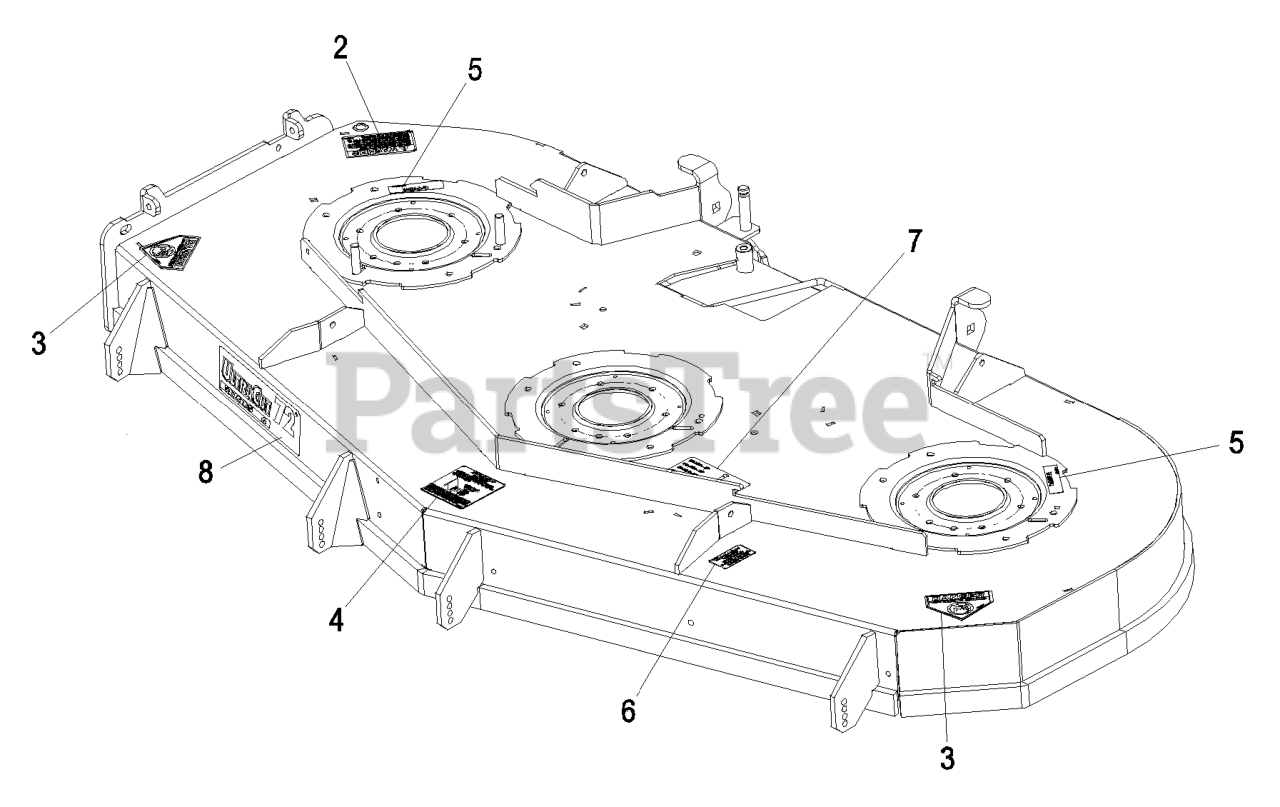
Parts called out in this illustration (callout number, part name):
2	DECAL-WARNING, DISCHARGE
3	DECAL-DANGER
4	DECAL,ANTISCALP
5	DECAL-COVER, MISSING
6	DECAL,BOLT TORQUE
7	DECAL,BELT ROUTING
8	DECAL,ULTRACUT 72 SERIES
